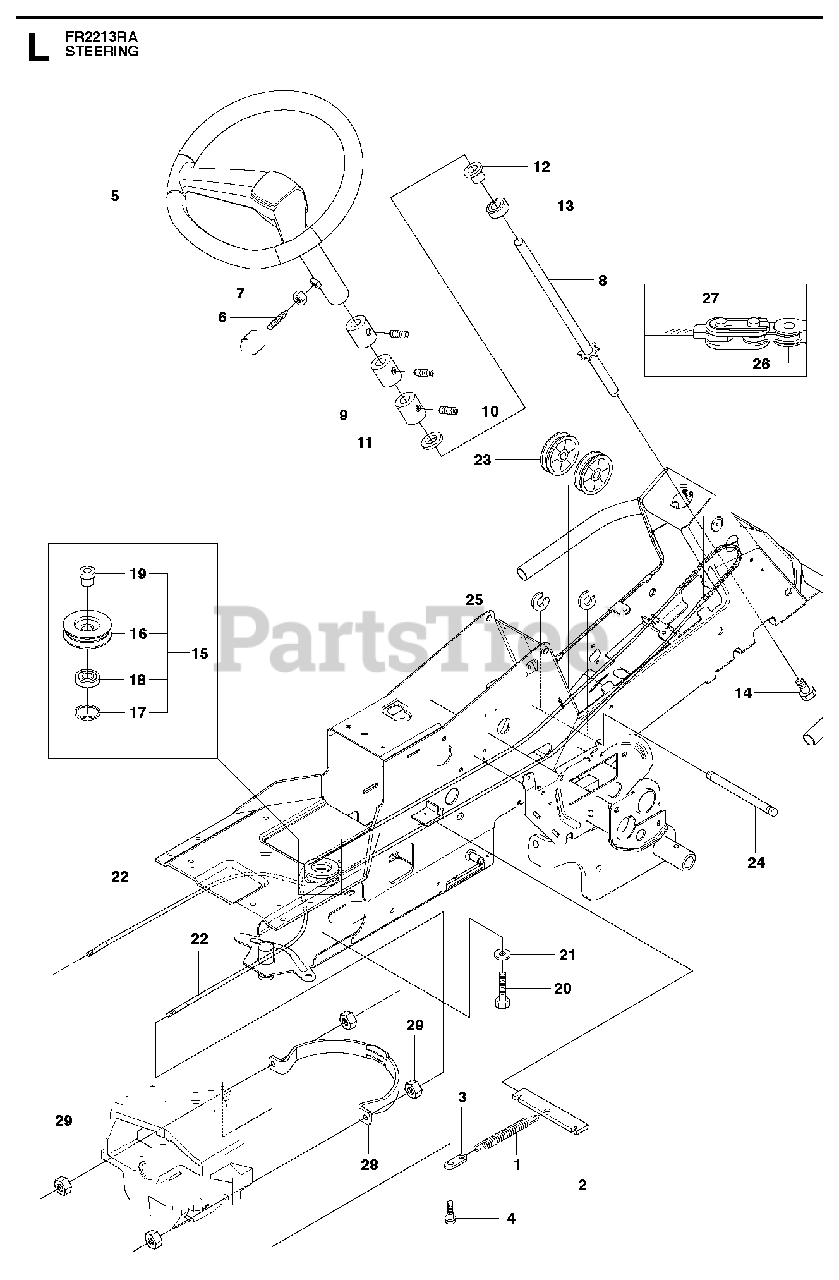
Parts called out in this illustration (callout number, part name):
2	SPRING BRACKET
3	CONNECTOR
5	STEERING WHEEL
7	NUT
8	ROD STEERING ASSY
13	BALL BEARING 6004-2RS1
16	ROLLER
17	CIRCLIP SGH 47
18	BALL-BEARING 6204-2RS
19	BUSHING
20	COLLAR SCREW
22	RP STEERING CABLE COMPLETE
25	RETAINING RING
26	STEERING CHAIN
28	WIRE GUIDE
